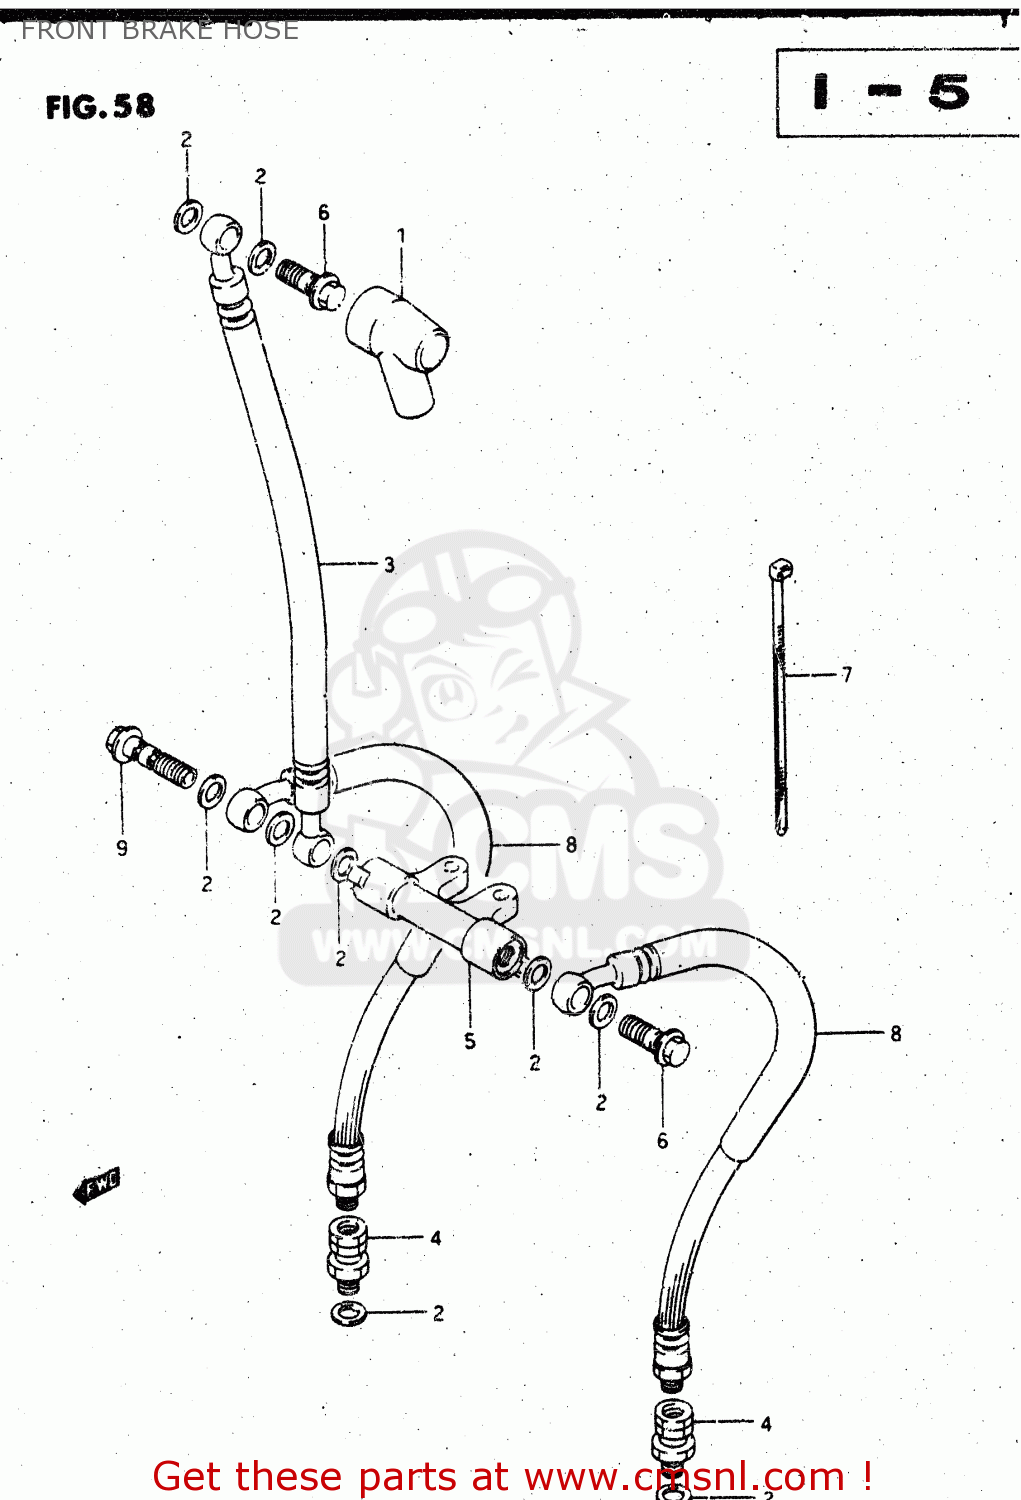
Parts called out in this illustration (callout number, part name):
1	BOOT,MASTER CYLINDER
2	WASHER(10X15X1.5)
3	HOSE,FRONT BRAKE
4	ADAPTER
5	JOINT,BRAKE HOSE
6	BOLT UNION
7	CLAMP(L:250)
8	HOSE,FRONT BRAKE
9	BOLT UNION
